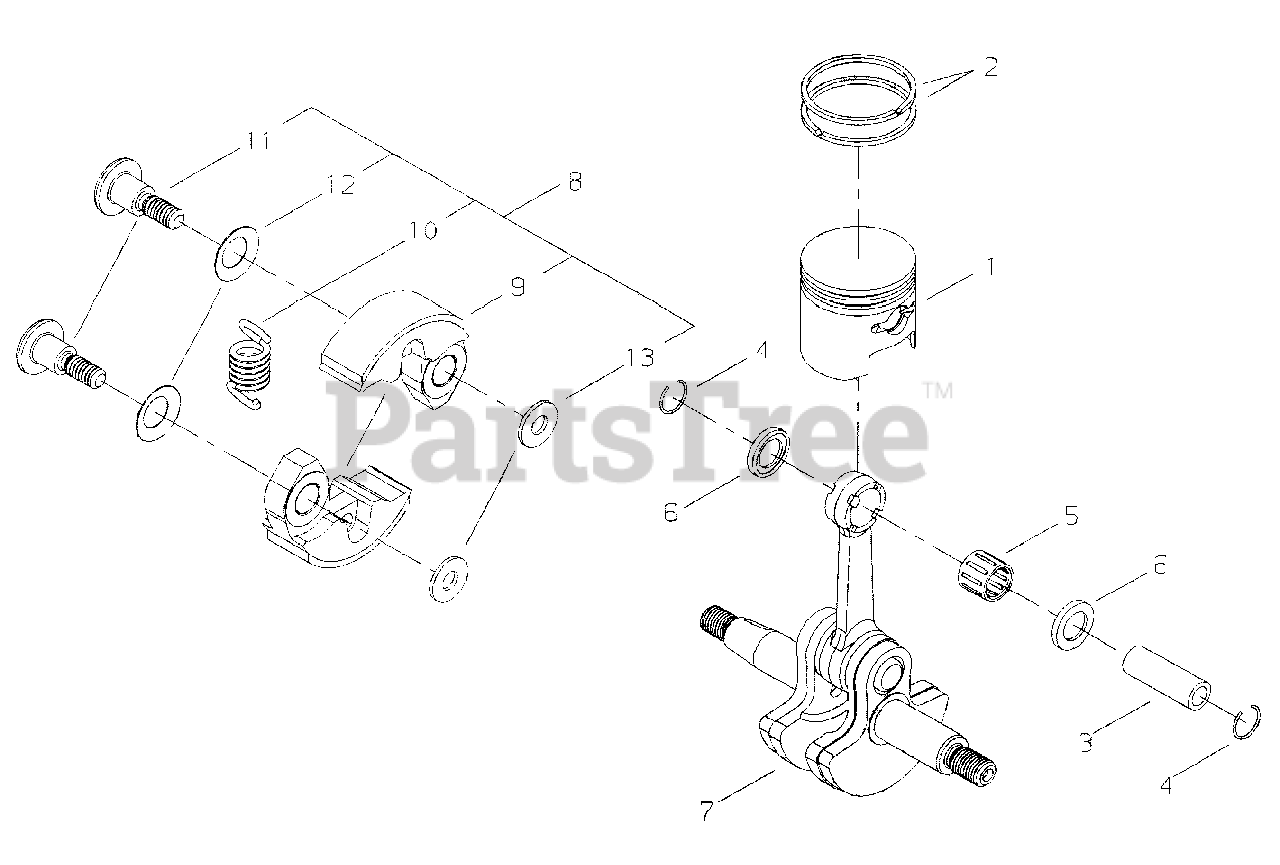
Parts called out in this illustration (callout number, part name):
1	PISTON
2	RING, PISTON
3	PIN, PISTON
4	RING, SNAP
5	BEARING, NEEDLE 9
6	WASHER, THRUST 9
7	CRANKSHAFT
8	CLUTCH ASSY
9	SHOE, CLUTCH
10	SPRING, CLUTCH
11	BOLT, CLUTCH
12	WASHER, SPRING
13	WASHER 6 MM
